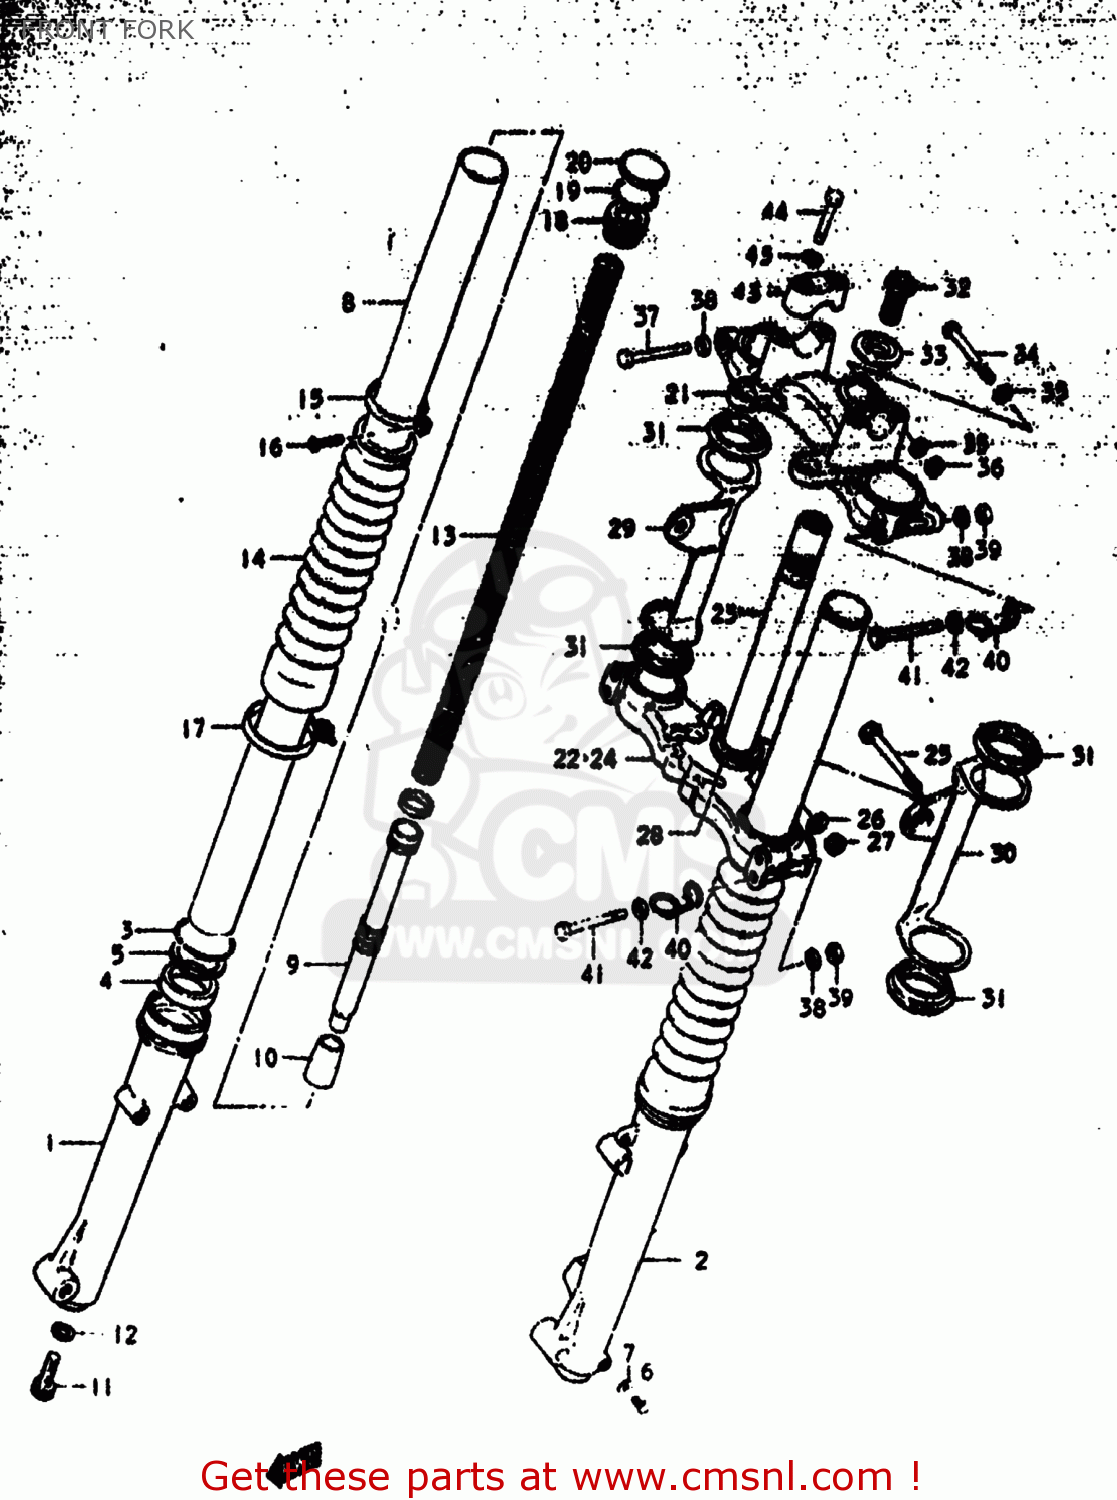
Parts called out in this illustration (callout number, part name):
0	DAMPER ASSEMBLY,LEFT
1	TUBE,OUTER,RIGHT
2	TUBE,OUTER,LEFT
3	CIRCLIP,FORK OIL SEAL
4	OIL SEAL,FRONT FORK
5	RING,FORK BACK UP
6	SCREW
7	GASKET,DRAIN,PLUG (NAS)
8	TUBE,FORK,INNER
9	CYLINDER,FRONT FORK
10	PIECE,OIL LOCK
11	BOLT,FORK CYLINDER(10X25)
12	GASKET (NAS)
13	SPRING
14	BOOT
15	BAND,BOOT
16	SCREW
17	BAND,FRONT FORK COVER
18	CAP,FORK INNER TUBE
19	O RING
20	CAP,FRONT FORK
21	HEAD,STEERING STEM
22	STEM,STEERING
23	STEM,STEERING
24	STEM,STEERING
25	BOLT 10X60
26	LOCK WASHER
27	NUT
28	RACE,STEERING OUTER LWR
29	BRACKET,HEADLAMP,RIGHT
30	BRACKET,HEADLAMP,LEFT
31	CUSHION,HEADLAMP BRACKET
32	BOLT,STEERING STEM HEAD
33	WASHER
34	BOLT 8X55
35	WASHER
36	NUT 8MM
37	BOLT 8X55
38	WASHER
39	NUT 8MM
40	GUIDE,CABLE
41	BOLT
42	WASHER
43	HOLDER,HANDLEBAR
44	BOLT
45	LOCK WASHER
